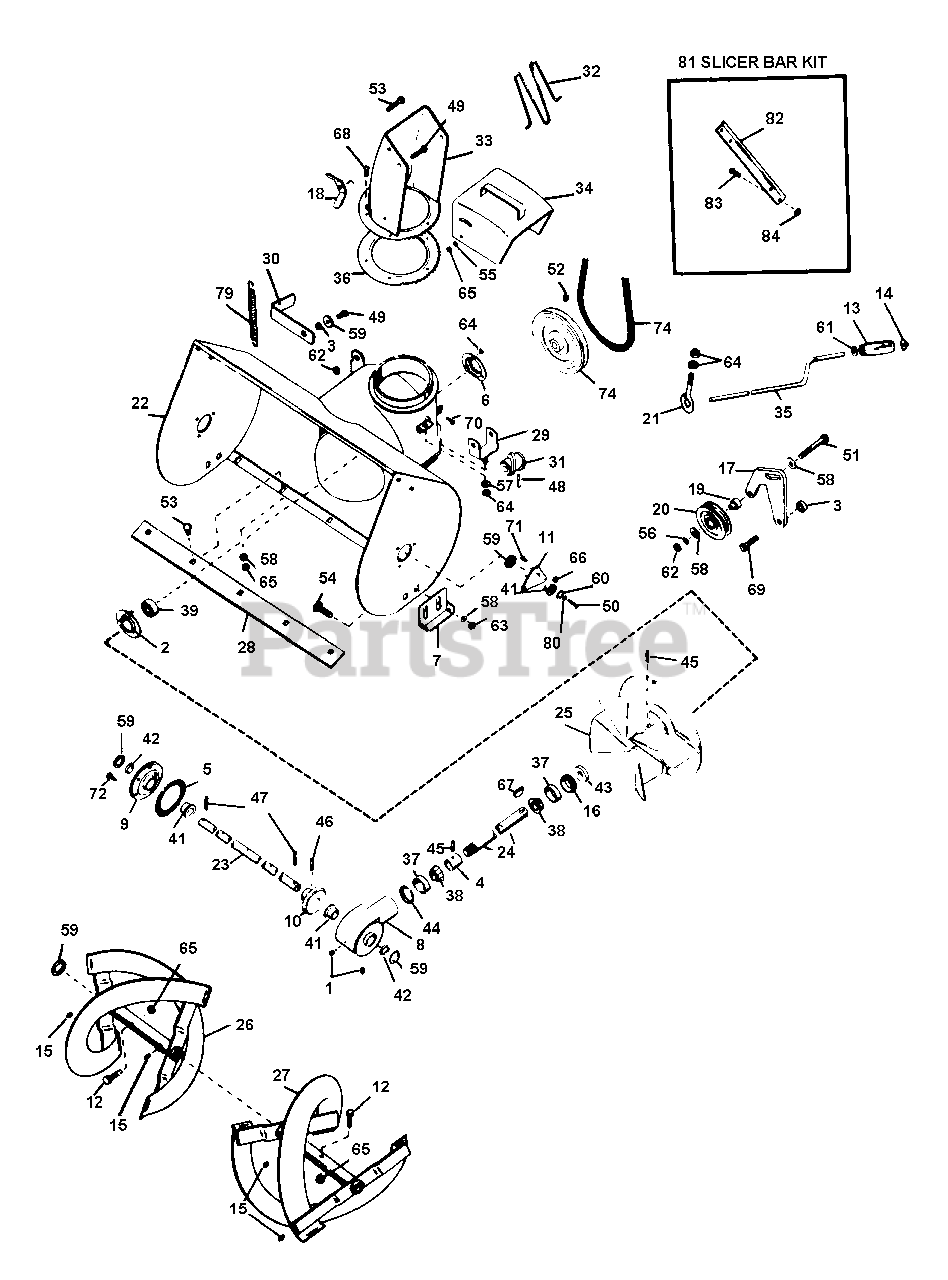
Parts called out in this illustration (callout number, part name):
1	PIPE PLUG
2	BEARING FLANGE
3	SPACER BUSHING .5 X .32 X .21
4	BEARING SPACER
6	BEARING FLANGE
7	RUNNER
8	CASE, GEAR - C.I.
9	GEAR CASE FLANGE
10	HELICON GEAR - 41 TOOTH
11	BEARING SUPPORT
12	SHEAR BOLT YWZC
14	CAP, 3/8 ROD YWZC
15	HYDRAULIC DRIVE FITTING
16	ADJUSTMENT PLUG
17	IDLER ARM
18	WING NUT, .312-18
19	SPCR, BRG .315X.50X.688X.281
20	IDLER
21	EYEBOLT
22	BLOWER HOUSING
23	FRONT GEAR SHAFT
24	SHAFT
26	R H RAKE
27	L H RAKE
28	SCRAPER BLADE
29	WORM CLEVIS
30	CLTCH LEVER
31	WORM GEAR
32	SAFETY WIRE
33	DISCHARGE CHUTE
34	DEFLECTOR CHUTE
35	CNTL CRANK
36	LOWER COLLAR GEAR
37	BRG-CUP 1.781X.475
38	BRG-CONE .750X.61
39	BRG-BALL .750X1.750X.50
40	BRG-BALL .500X1.38X.437
41	BSHG-FLG 1.000X1.12X.62X1.50BR
42	SEAL 1.000X1.312X.150
43	SEAL .750X1.499X.225
44	RG-RTNG INT 1.781 HSG X.062
45	PIN-ROLL .250X1.25
46	PIN-ROLL .313X1.38
47	PIN-ROLL .188X1.50
48	PIN-ROLL .125X.75
49	BLT-HEX .31-18X.75 PL GR2
50	BLT-HEX .50-13X1.00 PL GR2
51	BLT-HEX .31-18X1.50 PL GR2
52	SCR-SET .32-18X.38 SKHCUPNL OH
53	BLT-RDHDSQSHNK .31-18X.50 YZ
54	BLT-RDHDSQNK .38-16X.75 SHT PL
55	WSHR-LK .250X.077 HVY PL
56	WSHR-LK .312X.097 PL HVY
57	WSHR-FL-STL .250X.562X.049 PL
58	WSHR-FL-STL .38X.875X.083 PL
59	WSHR-FL-STL 1.010X1.505X.062PL
60	WSHR-FL-STL .511X1.441X.125 PL
61	WSHR-FL-STL .382X.812X.023 PL
62	NUT-HEX .312-18
63	NUT-LK-CTR .375-16 GR A PL
64	NUT-LK-CTR .250-20 PL
65	NUT-LK .312-18 GR A PL
66	NUT-LK-FLG .250-20 PL
67	KEY-WDRF .188X.75X.313 SAE 9
68	RVT-POP.125 X .294 DOME
69	BLT-SERHFWH .31-18X.50 PL
70	BLT-SCRHFWH .38-16X.50 PL
71	SCR-SLTR-SERNK .25-20X.62 PL
72	BLT-SERHFWH .25-20X.75 PL
73	V-BELT, 4L-WRAPPED
74	PLY-? 8.0X.75
75	SNO-THRO HELICON PATENT LABEL
76	SNO-THRO DECAL
77	CAUTION LABEL
78	IN OUT LABEL
79	SG-TENS .125X.437X5.5 WLD 20
